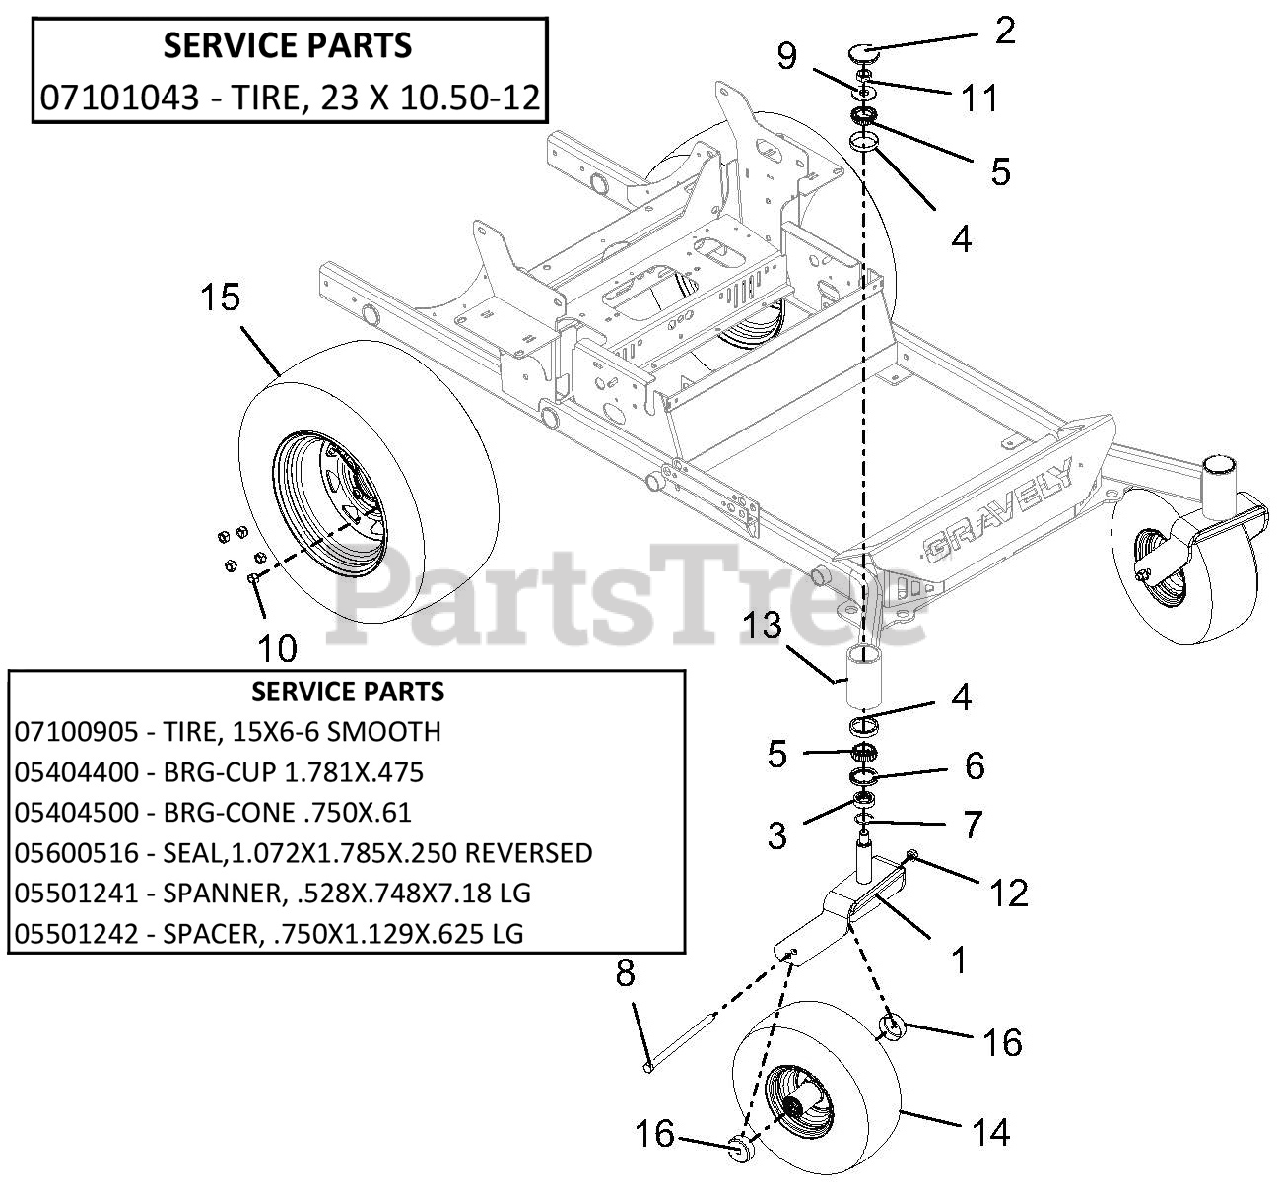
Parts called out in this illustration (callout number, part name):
1	CASTER FORK WMT - RED
2	CAP, DUST
3	SPCR, FRONT CASTER FORK
4	BRG-CUP 2.328X.465
5	BRG-CONE 1.25X.66
6	SEAL, OIL 1.75 X 2.332 X .312
8	@BLT-HEX .50-13X9.00 GR5 YWZC
9	@WSHR-FL-STL.812X2.00X.148YWZC
10	WHEEL NUT .500-20 YZ
11	NUT-JAM CTRLK .75-16 YWZC
12	@NUT-LK-TOP-FLG .50-13 YWZC
13	FTG, .25-28 FLUSH MNT GREASE
14	TIRE/WHEEL 15X6.00-6 SMOOTH
14	TIRE, 15X6-6 SMOOTH
14	BRG-CONE .750X.61
14	BRG-CUP 1.781X.475
14	SEAL,1.072X1.785X.250 REVERSED
14	SPANNER, .528X.748X7.18 LG
14	SPACER, .750X1.129X.625 LG
15	TIRE/WHEEL ASSM, 23X10.5-12
15	TIRE, 23 X 10.50-12
16	SHIELD, WHEEL BEARING
